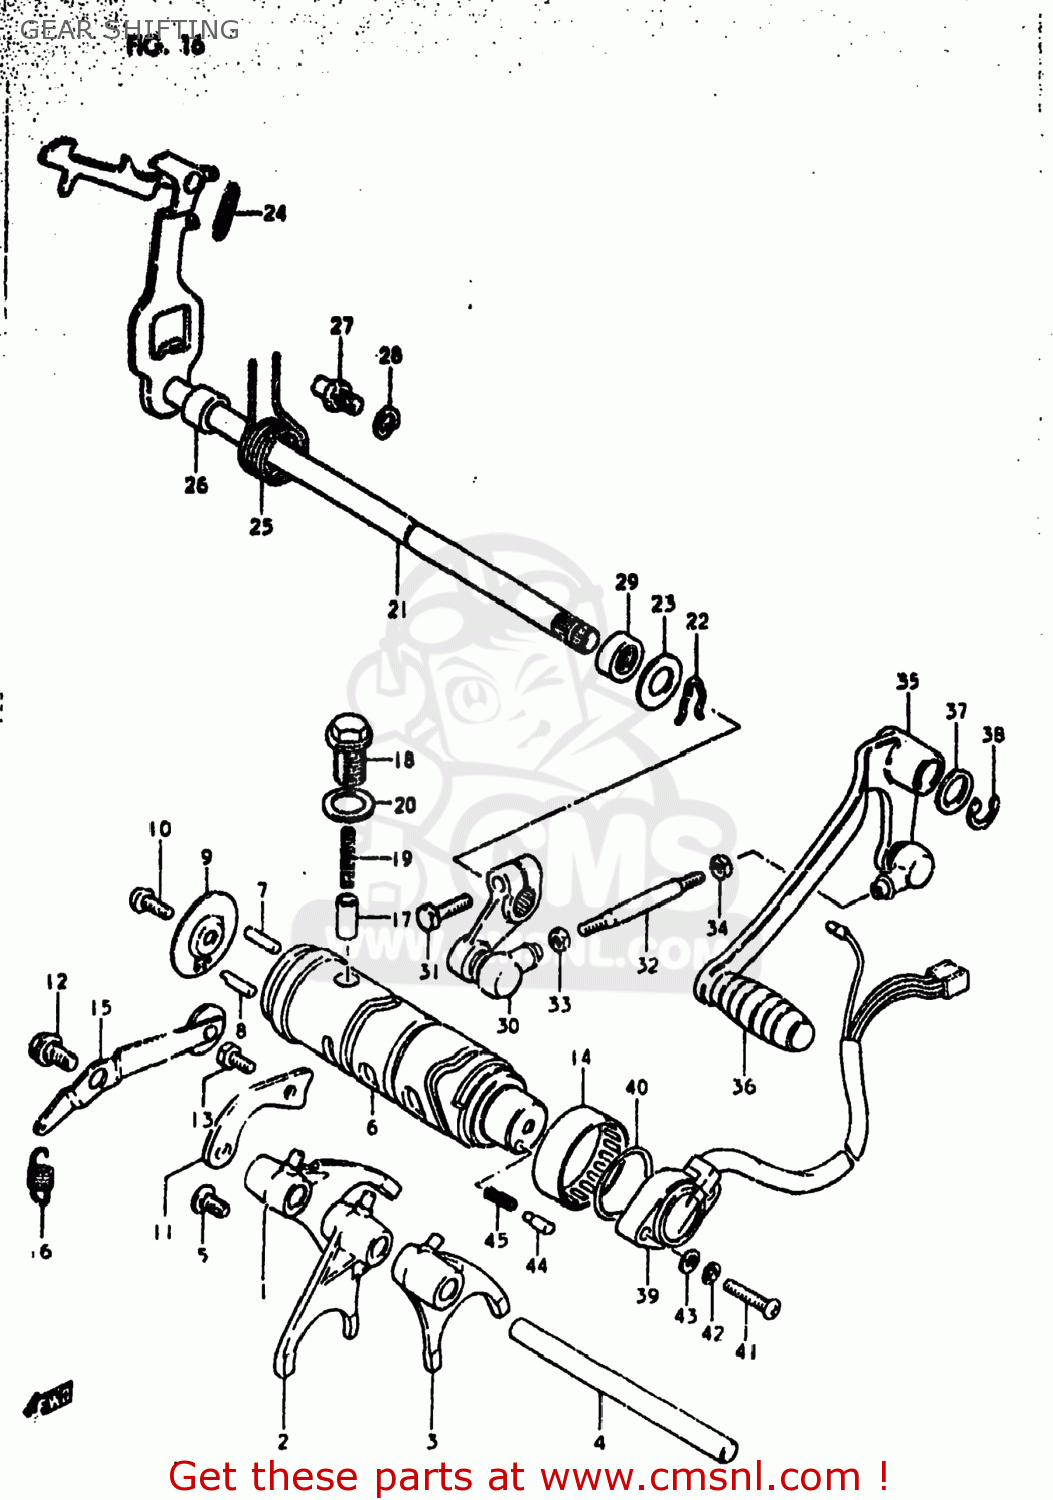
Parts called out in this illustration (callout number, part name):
1	FORK,GEAR SHIFT NO.1
2	FORK,GEAR SHIFT NO.2
3	FORK,GEAR SHIFT NO.2
4	SHAFT,GEAR SHIFT FORK
5	SCREW
6	CAM,GEAR SHIFT
7	PIN(4X18.5)
8	PIN
9	RETAINER,GEAR SHIFT CAM DR PIN
10	SCREW
11	GUIDE,GEAR SHIFTING CABLE
12	BOLT
13	BOLT
14	BEARING(40X47X12)
15	STOPPER,GEAR SHIFT CAM NO.1
16	SPRING
17	STOPPER,GEAR SHIFT CAM NO.2
18	HOLDER,GEAR SHIFT CAM STOP SPR
19	SPRING
20	GASKET(14X19.2X2) (NAS)
21	SHAFT,GEAR SHIFT
22	SPRING,RETAINER
23	WASHER (12.5X27X1.6)
24	SPRING
25	SPRING
26	SPACER(12X20X15.3)
27	STOPPER,GEAR SHIFT CAM
28	WASHER
29	OIL SEAL
30	ARM,GEAR SHIFT LINK
31	BOLT
32	ROD,GEAR SHIFT LINK
33	NUT
34	NUT
35	LEVER ASSEMBLY,GEAR SHIFTING
36	RUBBER,GEAR SHIFT PEDAL
37	WASHER(12.5X20X1)
38	CIRCLIP
39	TERMINAL BASE ASSY,GEAR SHIFT
40	O-RING (D:2.4 ID:26.2)
41	SCREW 5X20
42	LOCK WASHER
43	WASHER
44	PIN(5X15.5)
45	SPRING
